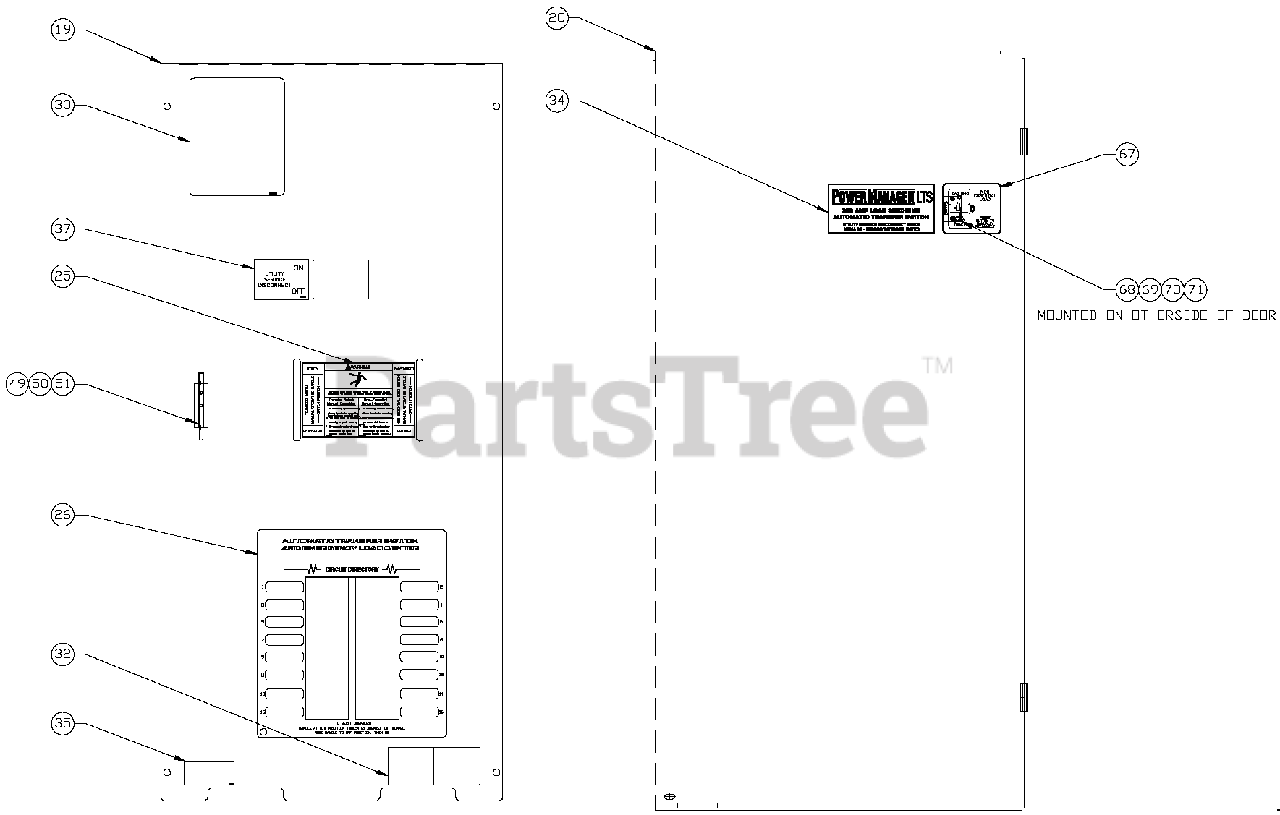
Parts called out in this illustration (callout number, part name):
19	INSIDE COVER LOAD SHED
20	COVER LOAD SHED ENCLOSURE
25	DECAL, WARN MANUAL OPER
26	DECAL, FRT GTS LD CTR 16 CIR
30	DECAL, TEST SEQUENCE
32	DECAL, TERMINAL SHOCK HZD BI
34	DECAL POWERMANAGER LTS
35	DECAL, LIVE CIRCUIT ENG/FRN/SPN
37	DECAL, UTILITY SERVICE
49	BRACKET, ARM EXTENDER
50	RIVET POP .156 X .362 AL
51	ARM EXTENDER PIN
67	KEYPAD, LOAD SHED
68	ASSY PCB INTFC LOAD SHED
69	NUT HEX LOCK M4-0.7 SS NYL INS
70	SPACER M4/#8 X 5/16 X 1/4 NYL
71	CABLE, KEYPAD INTERFACE
